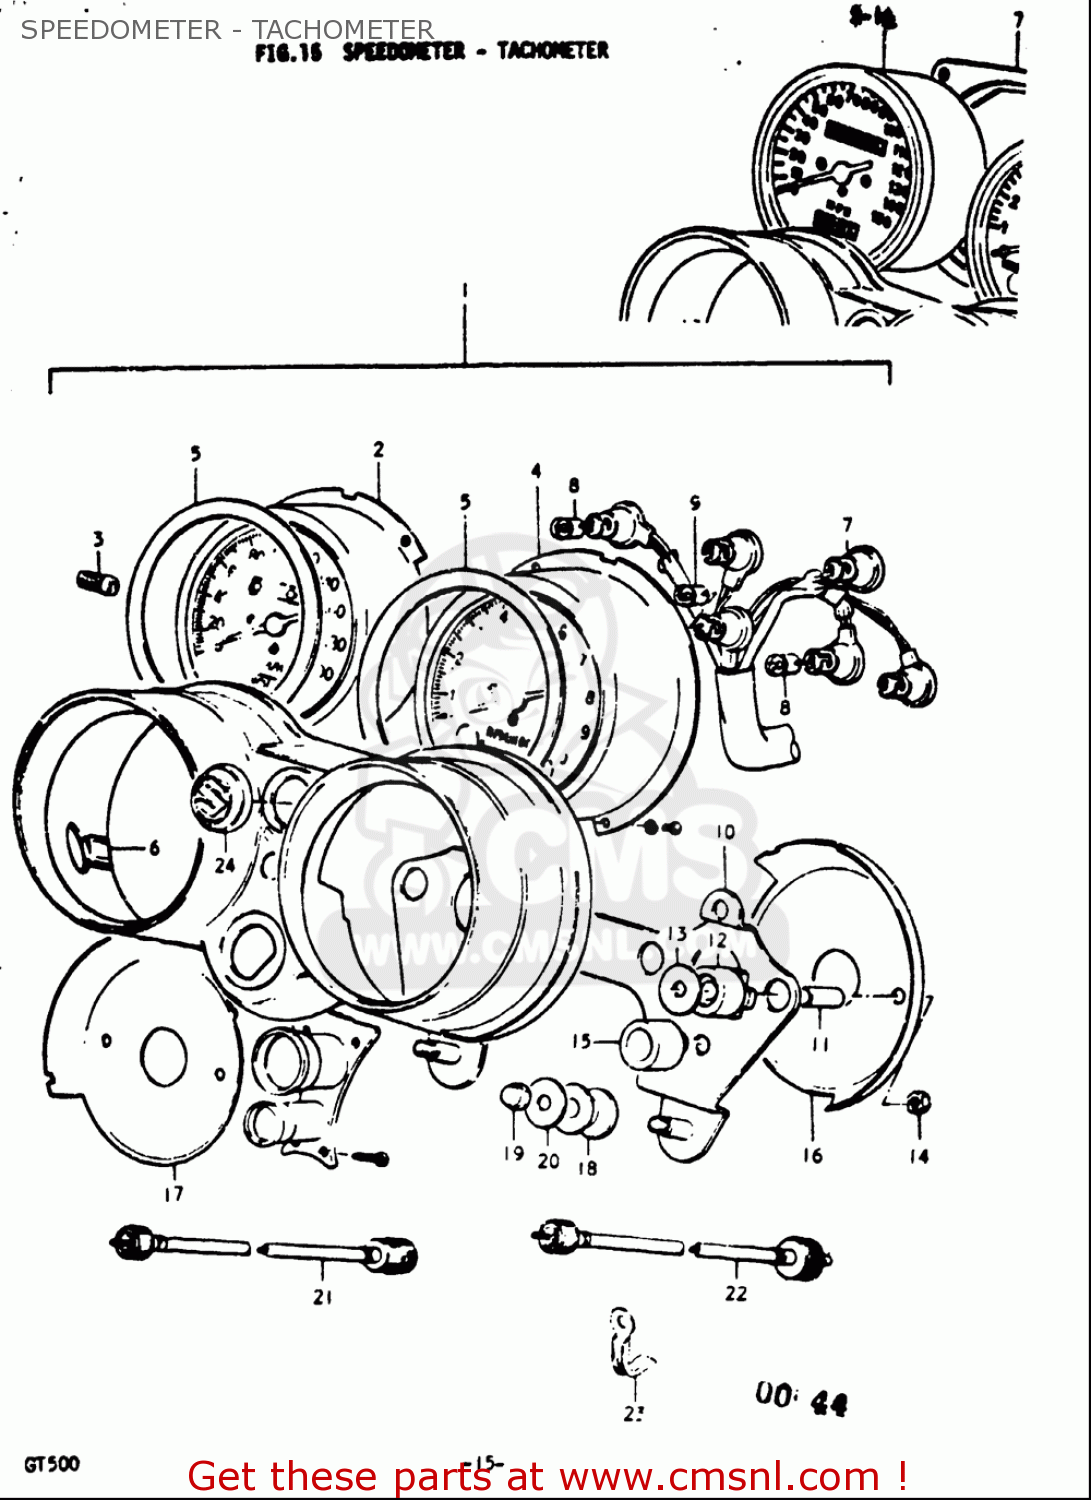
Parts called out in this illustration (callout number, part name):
3	KNOB, TRIP METER
6	CAP
8	BULB(12V3.4W,STANLEY,A72A)
9	BULB(12V1.7W,A71A)
12	CUSHION,METER NO.1
13	WASHER (5.5X18X1.6)
14	NUT
15	CUSHION,METER
18	CUSHION
19	NUT
20	WASHER(6.5X18X1.6)
21	CABLE ASSY,SPEEDOMETER
22	CABLE ASSY,TACHOMETER
23	LAMP ASSEMBLY
24	CAP,SPEED WARNER LAMP HOLE
